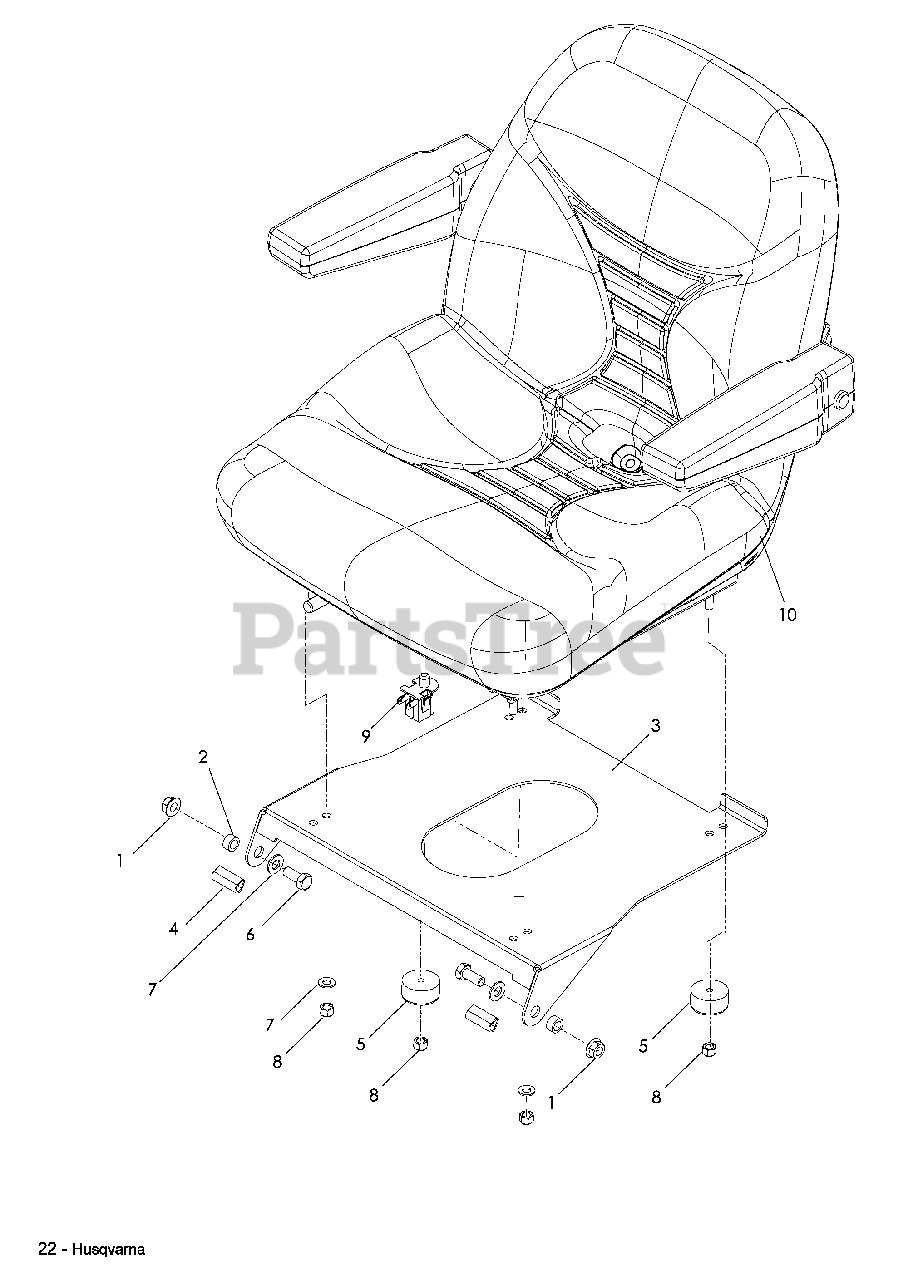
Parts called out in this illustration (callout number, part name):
1	NUT 5/16-18 FLANGE
3	SEAT PLATE
5	ISO MOUNT 1½ x ¾
6	HHB 5/16-18 x ¾
7	WASHER 5/16
8	NUT 5/16-18 NYLOC
9	SEAT SWITCH
10	SEAT
